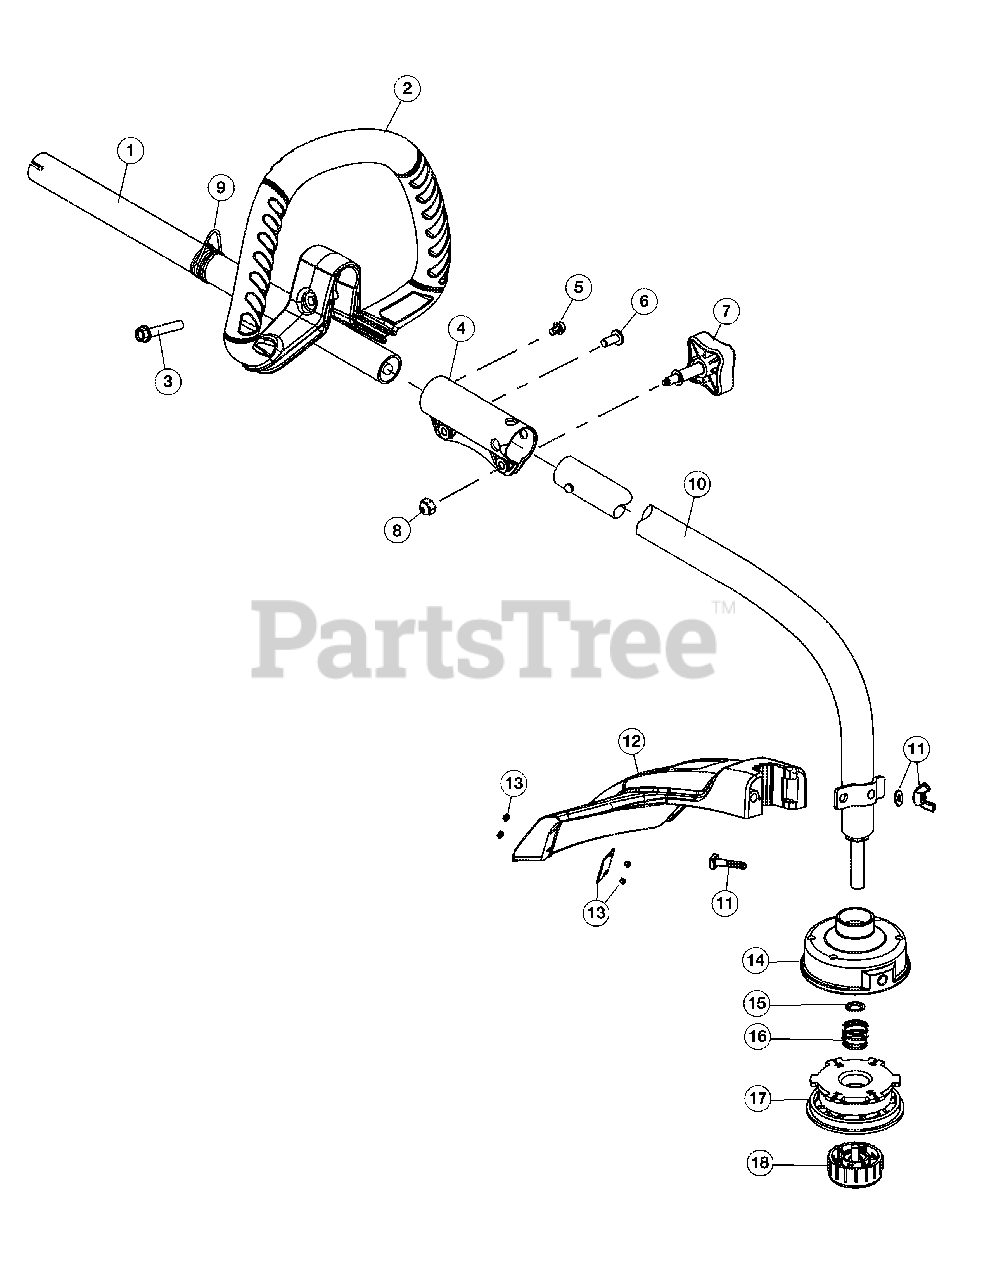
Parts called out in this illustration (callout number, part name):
1	Upper Drive Shaft Housing Assembly
2	D-Handle Assembly (Incl. 3)
4	Split boom Coupler (Incl. 5-8)
7	Adjustment Knob (Incl. 13)
8	Knob Retaining Nut
9	Shoulder Strap Spring
10	Lower Drive Shaft Housing Assembly
11	Shield Mounting Hardware
12	Shield Assembly (Incl. 11 & 13)
13	Blade Assembly
14	Outer Spool Assembly (Incl. 15)
17	Inner Reel
18	Bump Head Knob Assembly
